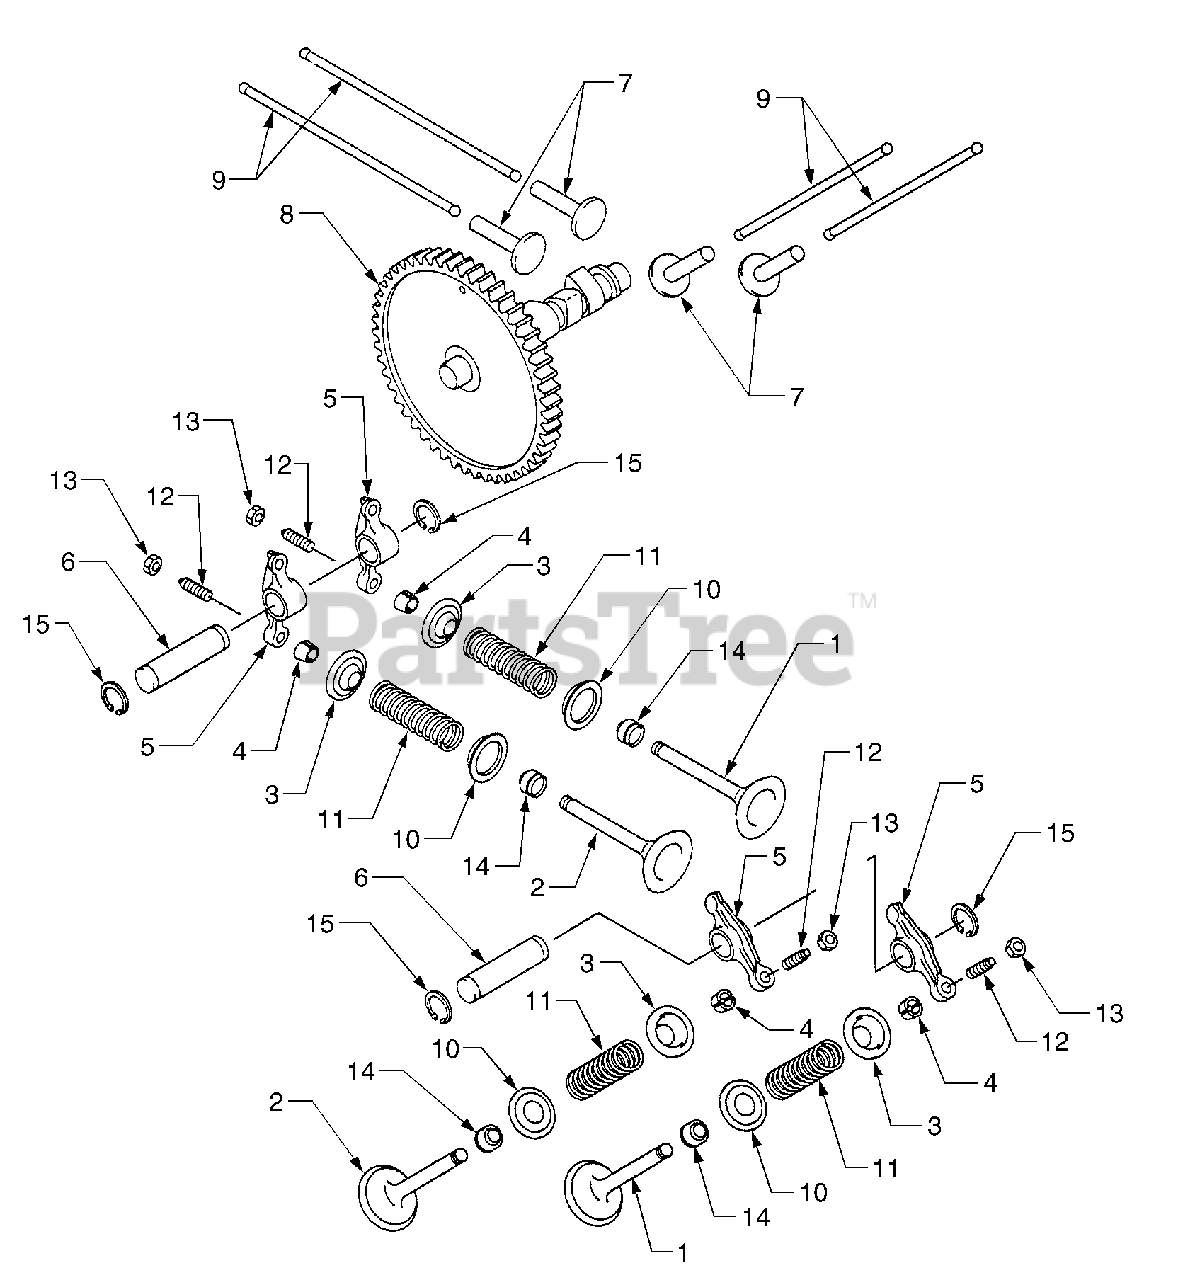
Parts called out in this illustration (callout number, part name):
1	Valve, Intake
2	Valve, Exhaust
3	Retainer, Valve Spring
6	Shaft, Rocker
8	Camshaft Assembly
10	Retainer, Spring
11	Spring, Valve
12	Screw, Valve Adjust
13	Nut, Valve Adjust Lock
